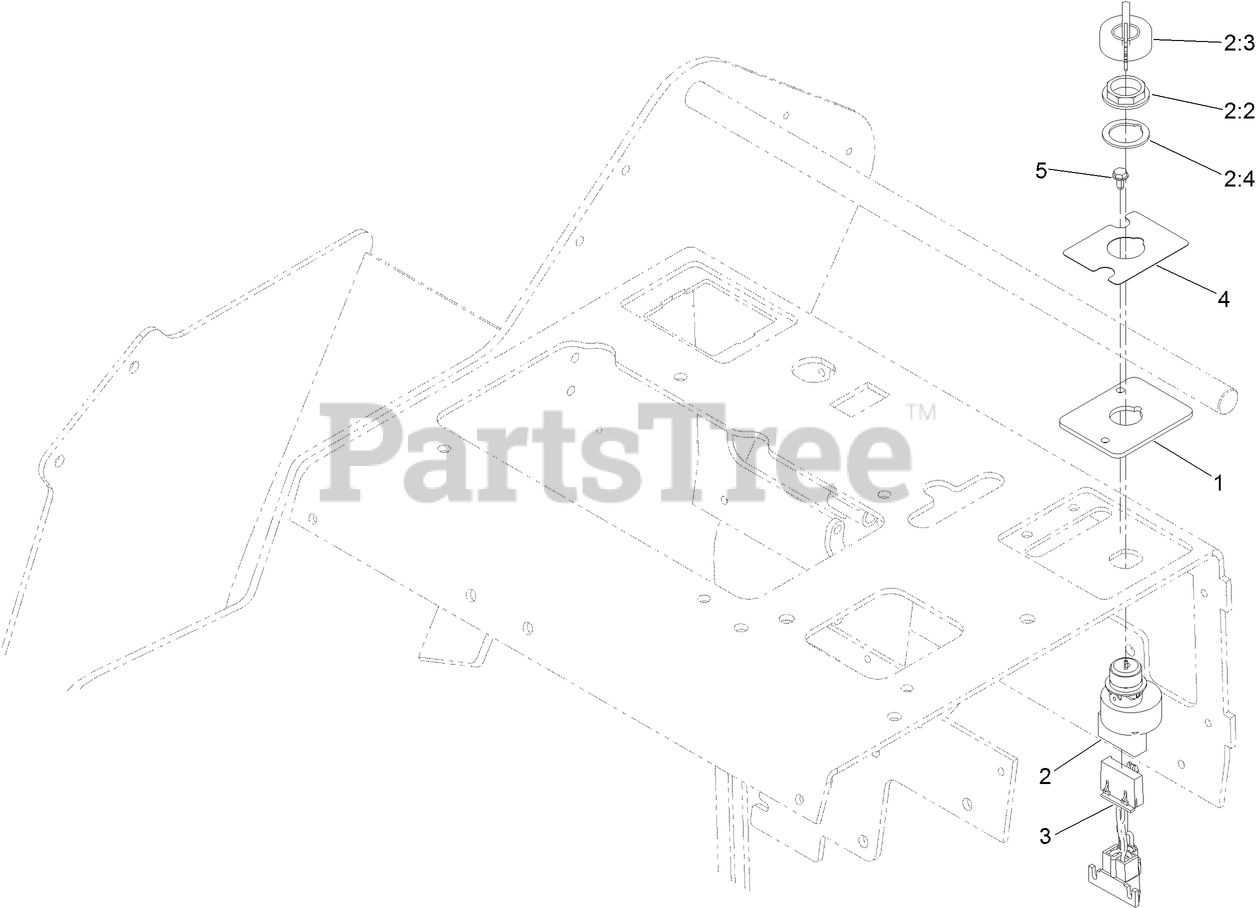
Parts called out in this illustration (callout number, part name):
1	PLATE-CONSOLE
2	IGNITION SWITCH ASM
2:2	NUT-MOUNTING
2:3	IGNITION KEY SET
2:4	WASHER-BACKUP
3	HARNESS-WIRE, ADAPTER
4	DECAL-IGNITION
5	SCREW-HWH
